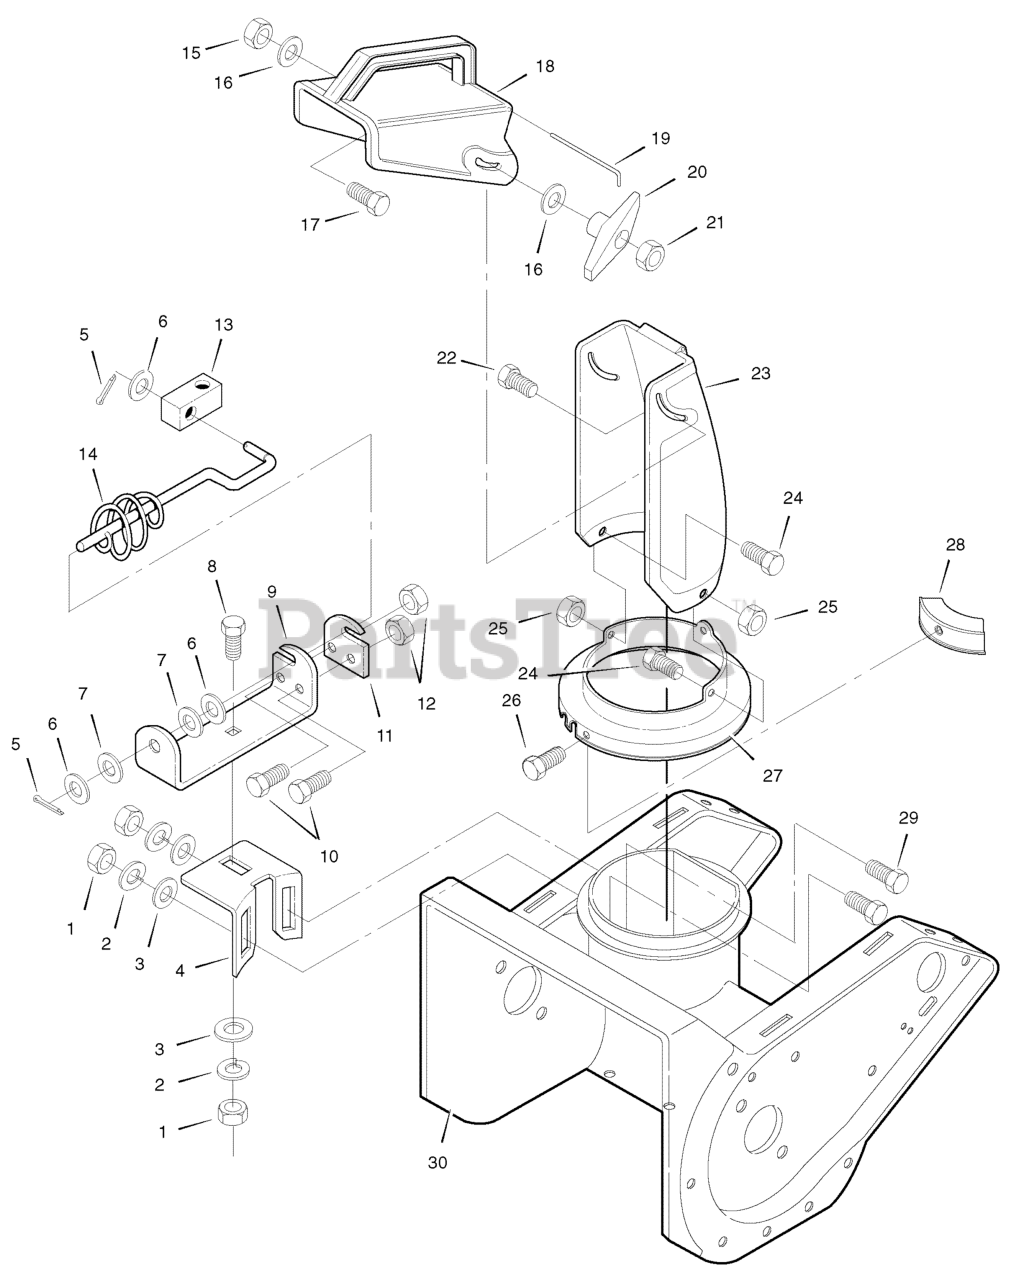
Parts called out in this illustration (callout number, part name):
1	NUT.31-18 HEX
2	WASHER, LOCK
3	WASHER, FLAT .349-0.69-.07
4	BRKT, WORM ADJUST
5	PIN, COTTER.094x0.75L
6	WASHER, FLAT .400-0.75-.02
7	WASHER, SPRING .395-0.73-.01
8	BOLT-CARRIAGE .31-18x0.75
9	BRKT, CHUTE ROD HOLE
10	SCREW.25-20x0.50 HHC
11	PLATE, CHUTE ROD
12	NUT, LOCK.25-20 HEX
13	BLOCK, PIVOT CHUTE
14	ROD ASSEMBLY, LOWER CHUTE
15	NUT, LOCK .31-18 HEX
16	WASHER, FLAT .349-0.69-.07
17	SCREW.31-18x0.75
18	CHUTE, UPPER
19	WIRE FORM, HINGE
20	WINGKNOB
21	NUT.31-18 HEX
22	BOLT-CARRIAGE .31-18x1.50
23	CHUTE, LOWER
24	SCREW.25-20x0.50
25	NUT, LOCK .25-20
26	SCREW.25-14x0.62
27	CHUTE RING
28	CLIP, CHUTE RING
29	BOLT-CARRIAGE .31-18x0.75
30	AUGER HSG, 21"
